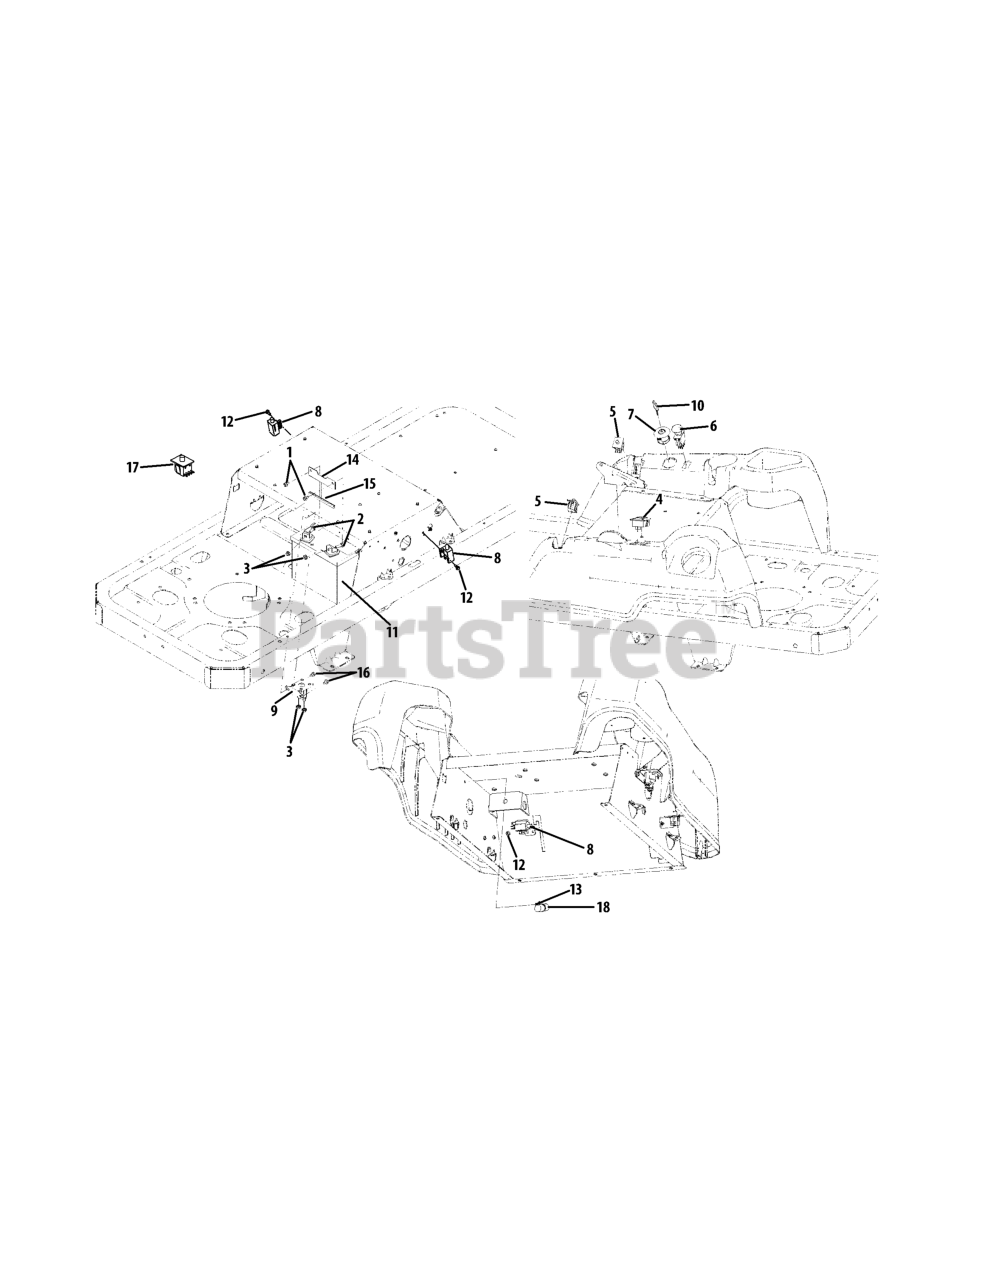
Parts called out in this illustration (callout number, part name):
1	Hex Screw, 1/4-20 x .5
2	Hex Screw, 1/4-20 x .75
3	Hex Nut, 1/4-20
4	Hour Meter
5	Double Pole - Neutral Switch
6	PTO Switch
7	Ignition Switch
8	Interlock Switch
9	Solenoid
11	Battery, 235 CCA
12	Shoulder Screw, #10-32 x .500
13	Cable Tie
14	Battery Hold-down
15	Trim Strip
16	Hex Screw, 1/4-20 x .375
17	Seat Switch
18	Wire Harness
